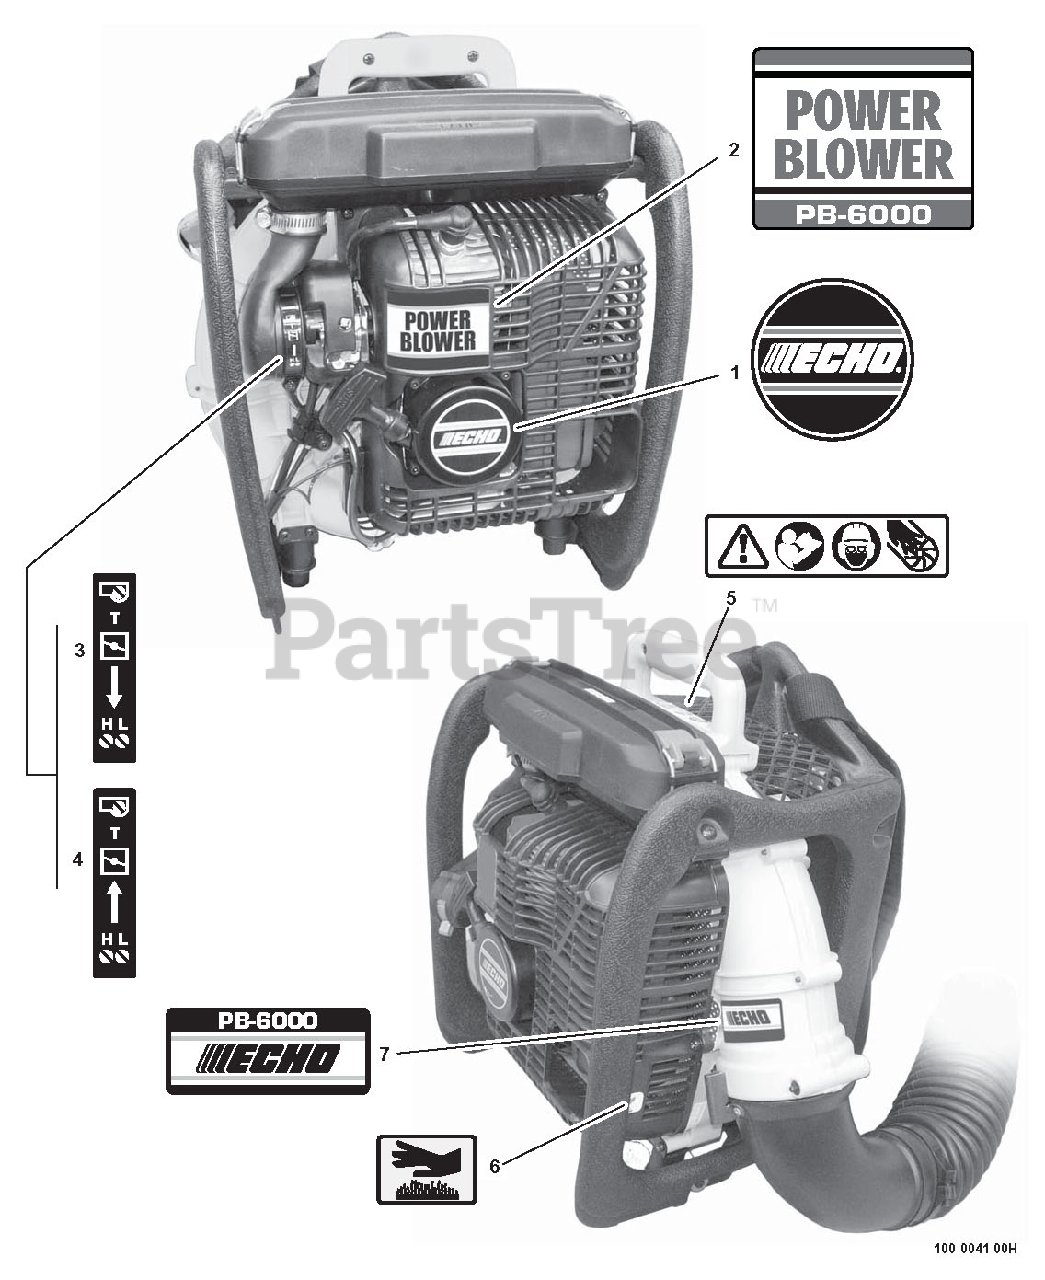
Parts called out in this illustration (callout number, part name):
1	LABEL - ECHO
2	LABEL - MODEL PB-6000
3	LABEL - CHOKE
4	LABEL - CHOKE
5	LABEL - CAUTION
6	LABEL - HOT SURFACE
7	LABEL - MODEL PB-6000
